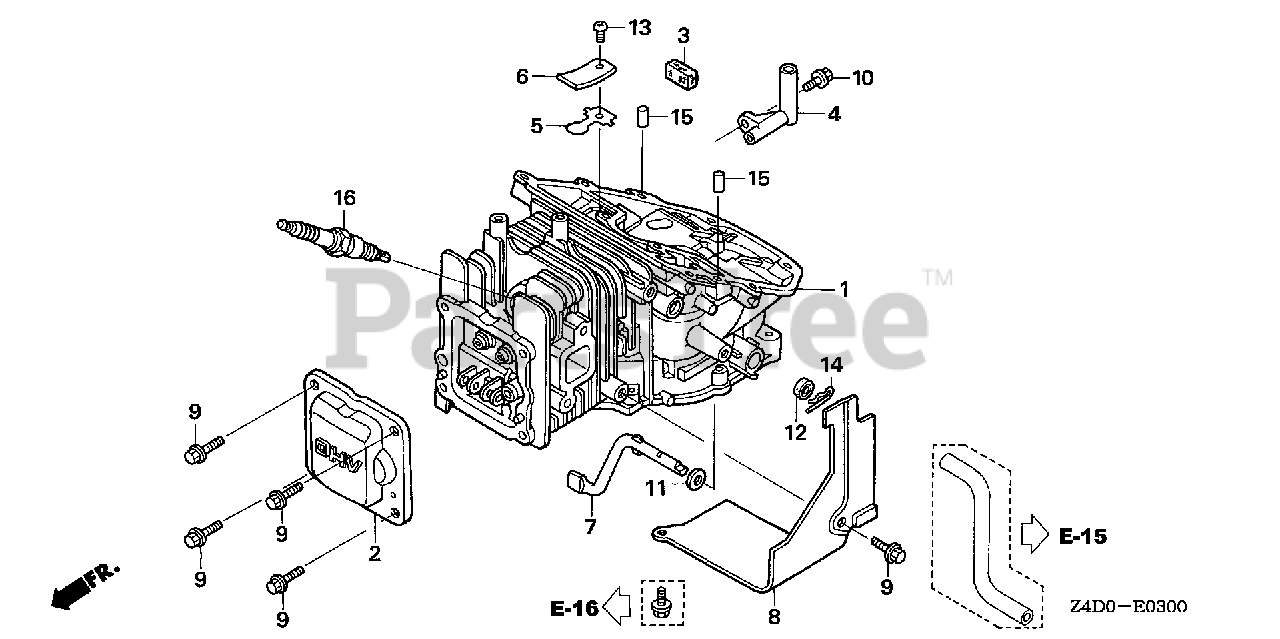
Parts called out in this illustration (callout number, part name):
2	COVER, HEAD
3	FILTER, BREATHER
4	PIPE, BREATHER
5	VALVE, OIL OUTLET
6	PLATE, STOPPER
7	SHAFT, GOVERNOR ARM
9	BOLT, FLANGE (5X12)
10	BOLT (4X10)
11	WASHER (5.2X9)
12	OIL SEAL (5X11X5)
13	SCREW, PAN (3X5)
14	PIN, LOCK (6MM)
15	ROLLER (6X14.8)
15	ROLLER (6X15)
16	SPARK PLUG (U14FSR-UB)
16	SPARK PLUG (CR4HSB)
16	SPARK PLUG (U16FSR-UB)
16	SPARK PLUG (CR5HSB)
